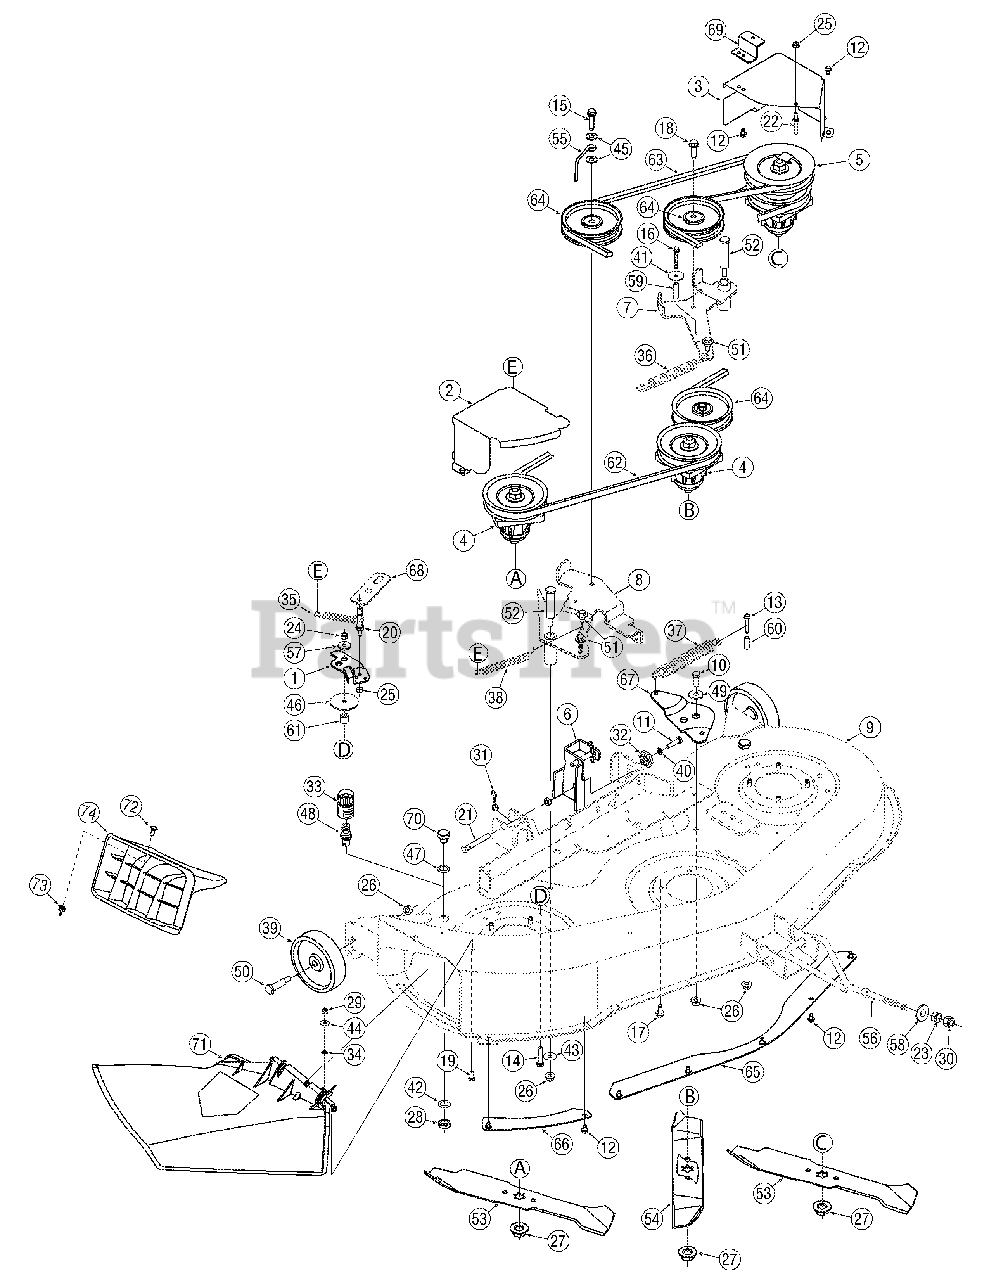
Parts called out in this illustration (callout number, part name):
1	Deck Brake Assembly
4	Spindle Assembly
5	Double Pulley Spindle Assy.
10	Hex Screw, 3/8-16 x 1.00
11	Hex Screw, 5/16-18 x 1.25
12	Screw, 1/4-20 x .50
13	Screw, 1/4-20 x 1.50
14	Hex Screw, 5/16-18 x 1.50
15	Sems Screw, 3/8-16 x 1.50
16	Screw, 1/4-20 x 1.75
17	Screw, 5/16-18, .750
18	Screw, 3/8-16, x 1.25
19	Screw, 1/4-20 x .75
20	Pin, 1/4-20: 3/8 x 2.685
21	Clevis Pin, 3/8 dia. x 2.75
22	Belt Guard Pin, 1/4 x 1.43 lg.
23	Hex Nut, 1/2-13
24	Flange Lock Nut, 5/16-18
25	Flange Lock Nut, 1/4-20
26	Flange Lock Nut, 3/8-16
27	Flange Nut, 5/8-18
28	Hex Nut, M16-1.5
29	Hex Nut, 1/4-20
30	Hex Lock Nut, 1/2-13
31	Bow-Tie Cotter Pin
32	Deck Adjustment Gear
33	Water Nozzle Adapter
34	Push Nut, .25 ID x .50 OD
35	Extension Spring, .50 x 3.97 Lg.
36	Extension Spring, .75 x 6.835 Lg.
37	Extension Spring, .91 x 7.33 Lg.
38	Extension Spring, .56 x 5.52 lg.
39	Deck Wheel 5.0 x 1.38
40	Lock Washer, 5/16
41	Flat Washer, .285 x 1.25 x .06
42	Lock Washer, 5/8 Int. Tooth
43	Flat Washer, .385 x 1.0 x .135
44	Bell Washer, .265 x .75 x .062
45	Flat Washer, .406 x .875 x .059
46	Flat Washer, .406 x .875 x .059
47	Flat Washer, .64 x 1.24 x .06
48	Deck Water Nozzle
49	Shoulder Spacer, .625 ID x .169
50	Shoulder Bolt .496 x 1.525: 3/8-16
51	Shoulder Screw .43 x .29:5/16-18
52	Shoulder Bolt .625 x 2.515: 3/8-16
53	Blade, 3 in 1 star, 16.28" Lg.
54	Blade, 3 in 1 star, 14.88" Lg.
55	Belt Keeper Rod
56	Front Deck Adjustment Rod
57	Shoulder Spacer
58	Deck Lift Pivot Cup
59	Spacer, .260 x .372 x 1.420 Lg.
60	Spacer, .260 x .372 x 1.030 Lg.
61	Spacer, .375 x .63 x .595 Lg.
62	V-Belt, 79.10 Lg.
63	V-Belt, 91.4 Lg.
64	Idler Pulley, 4.25" dia.
70	Bolt Plug, M16 x 1.5
71	Discharge Chute
72	Carriage Screw, 1/4-20 x .62
73	Wing Nut, 1/4-20
74	Mulch Plug, 46" Deck
